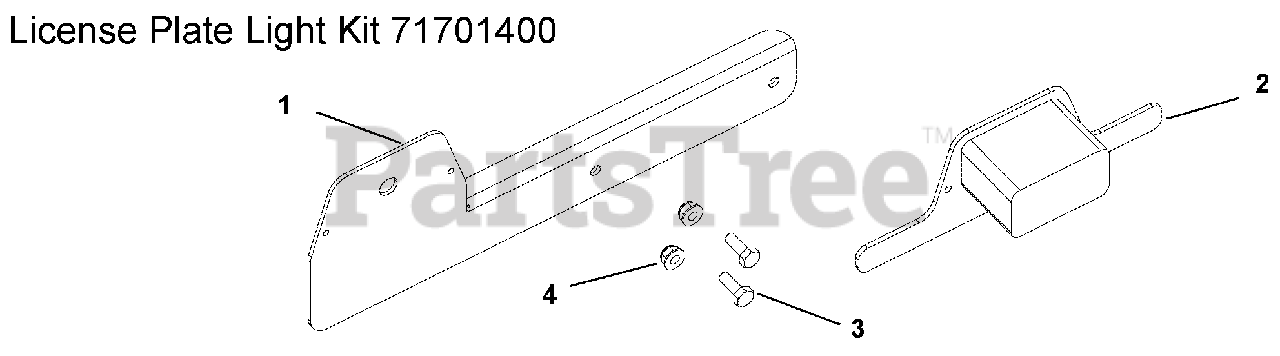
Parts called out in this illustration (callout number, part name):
1	BRKT, SPLITTER LICENSE PLATE
2	LICENSE PLATE BRACKET W/ LIGHT
3	@BLT-HEX .25-20X.75 GR5 YWZC
4	@NUT-LK-NYL-FLG .25-20 YWZC
